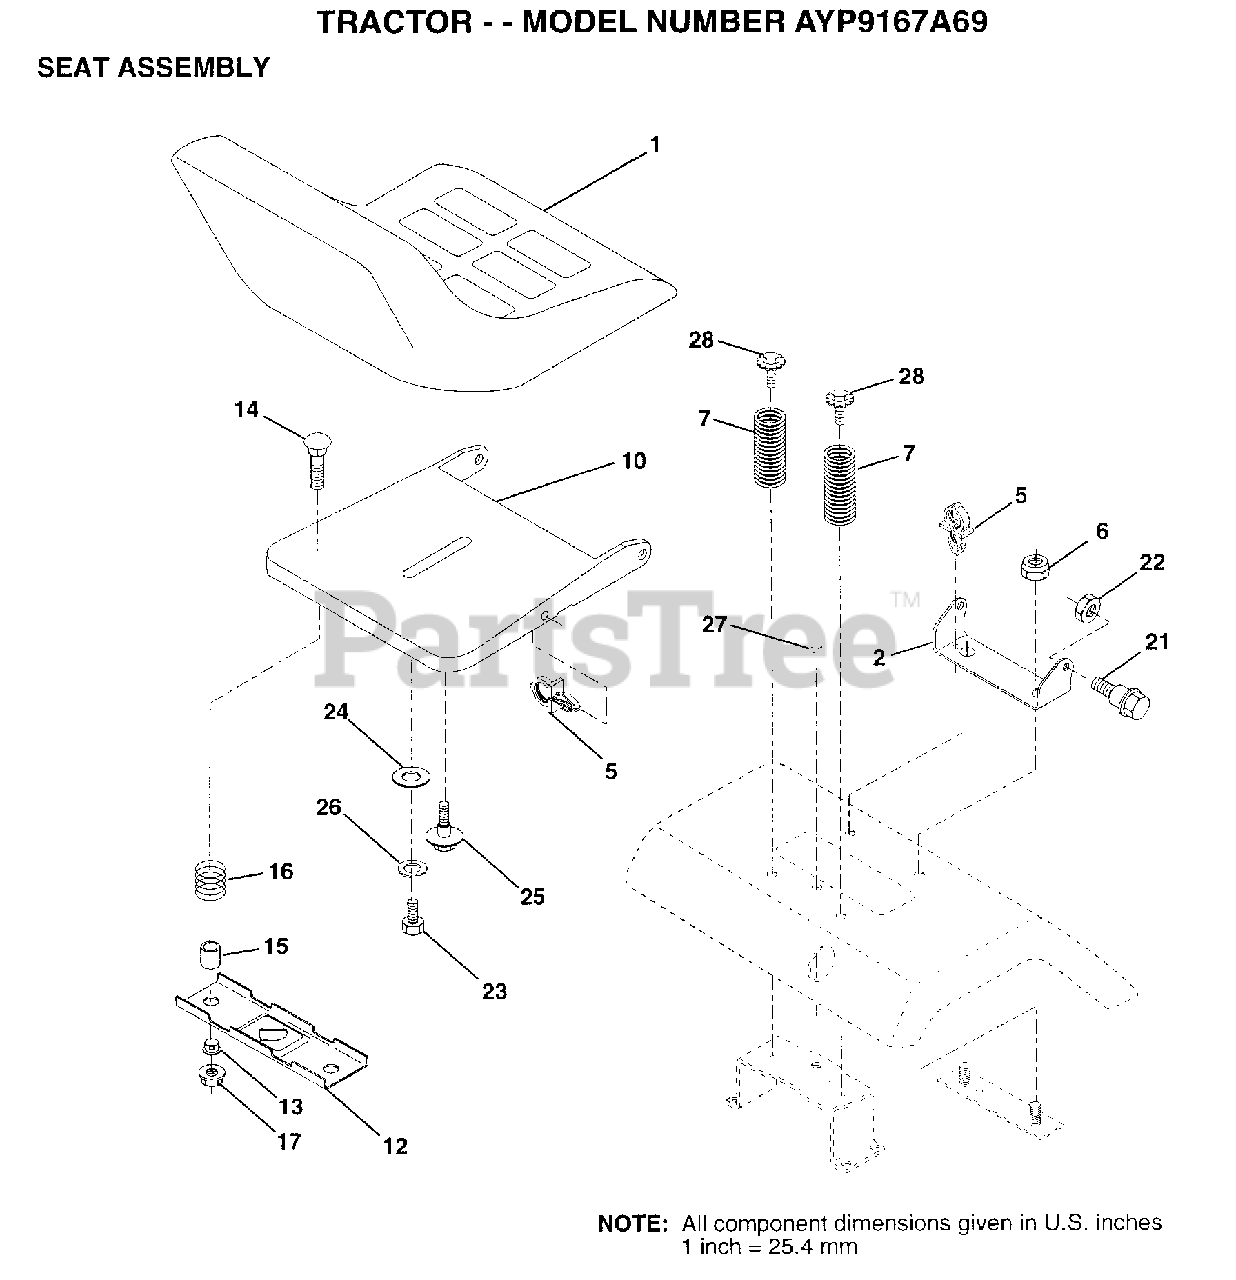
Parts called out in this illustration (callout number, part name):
1	SEAT.2400/1416.BK
2	BRACKET PVT SEAT
5	CLIP.PUSH-IN.HING
7	SPRING COMPRESSIO
8	SCREW LT
9	WASHER
12	BRKT SWITCH
13	BUSHING
15	SPLIT SPACER
16	SPRING
21	BOLT.SHLD.5/16-18
22	NUT
23	BOLT
24	WASHER
25	"BOLT,SHOULDER"
26	LOCKWASHER
27	SCREW LT
28	BOLT.5/16-18.UNC
